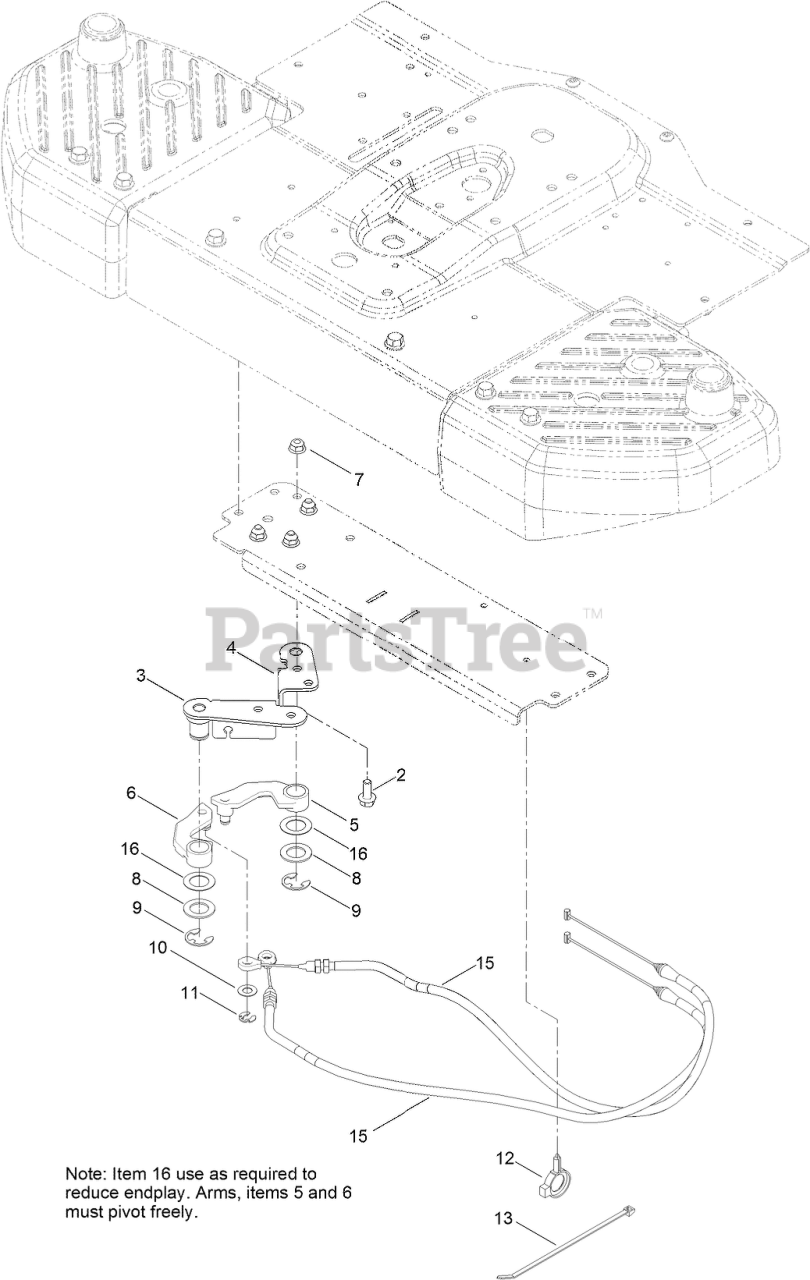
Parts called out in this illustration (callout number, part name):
2	SCREW-HHF
3	CABLE BRACKET ASM
4	CABLE BRACKET ASM
5	ARM-CABLE, RH
6	ARM-CABLE, LH
7	NUT-HF, NI
8	WASHER-THRUST
9	E-RING
10	WASHER-THRUST
11	RING-RETAINING
12	CLAMP-HOSE
13	TIE-CABLE
15	CABLE-STEERING
16	WASHER-THRUST
